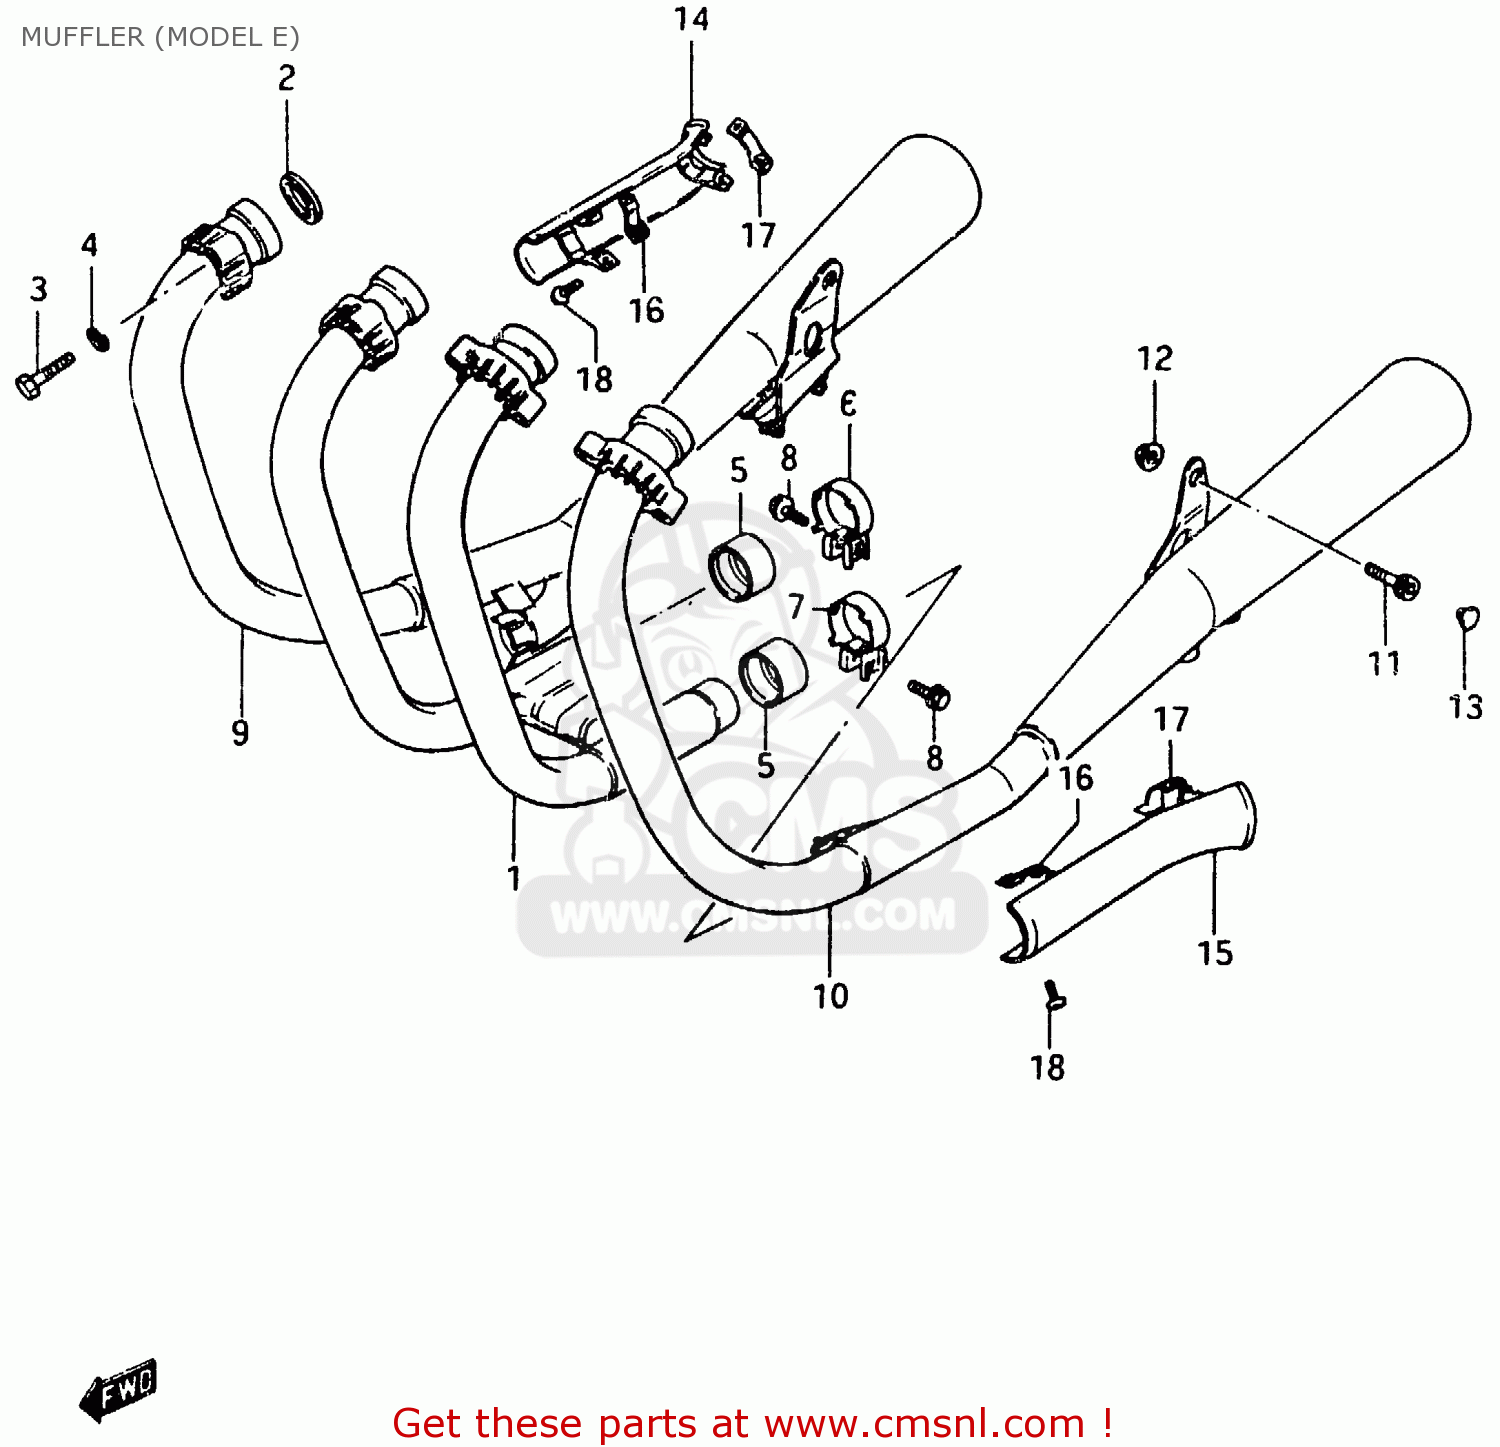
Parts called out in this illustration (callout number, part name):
1	PIPE,EXHAUST,CENTER
2	GASKET,EXHAUST PIPE (NAS)
3	BOLT 8X40
4	LOCK WASHER
5	CONNECTOR,MUFFLER
6	CLAMP,MUFFLER CONNECTOR
7	CLAMP,MUFFLER CONNECTOR
8	BOLT
9	MUFFLER, RH
10	MUFFLER, LH
11	BOLT 10X25
12	NUT
13	CAP
14	COVER,MUFFLER,RIGHT
15	COVER,MUFFLER,LEFT
16	CLAMP,MUFFLER COVER
17	CLAMP,MUFFLER COVER
18	SCREW
